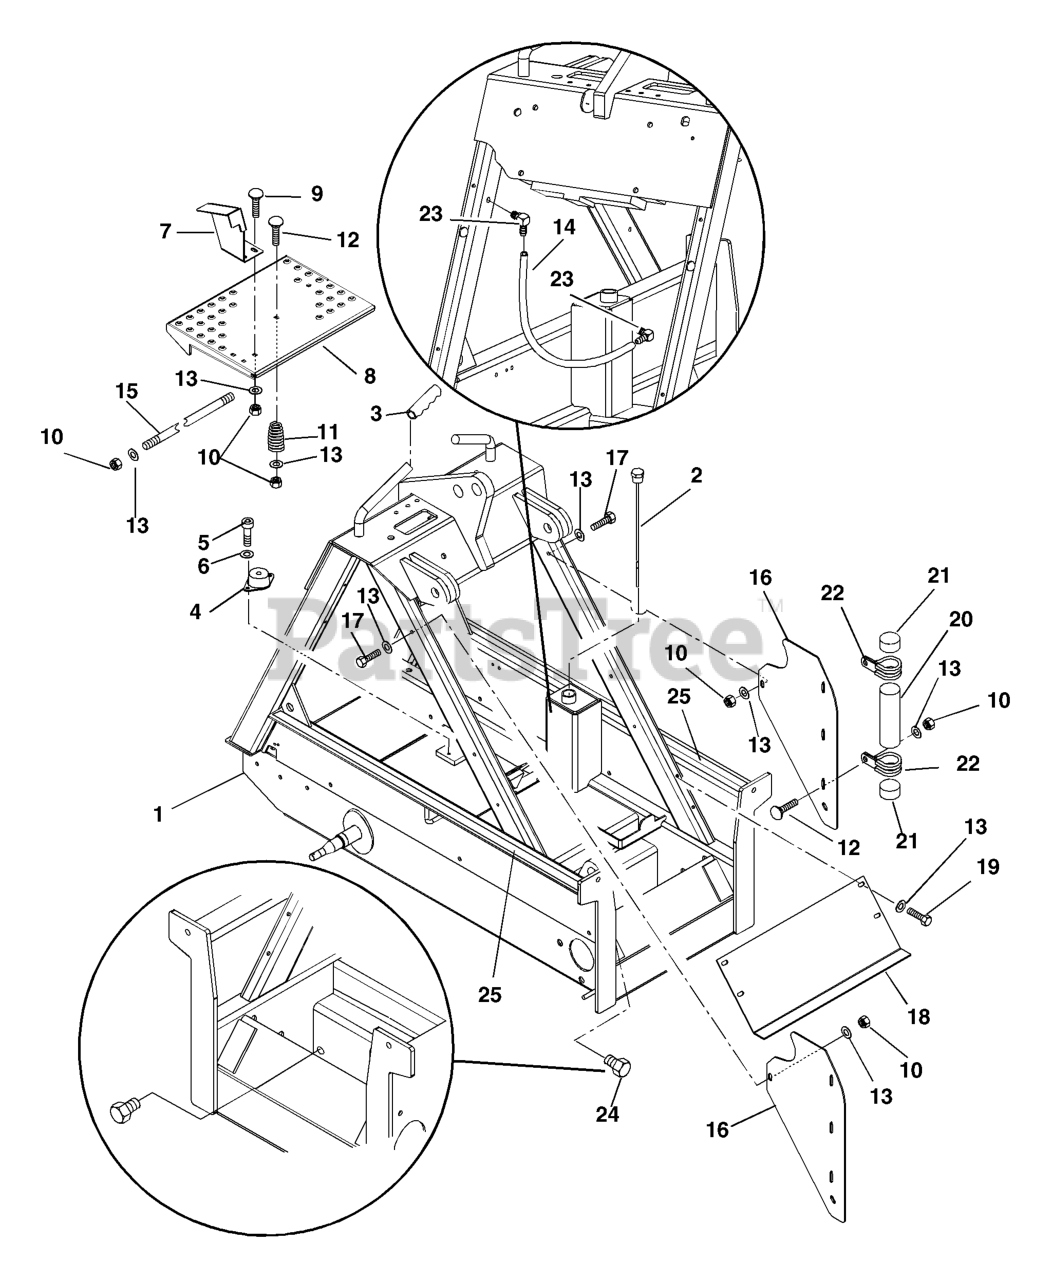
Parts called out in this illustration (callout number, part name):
2	Dipstick
3	Grip-Handle
4	Mount-Engine
5	Screw-Socket Head M8-1.25 x 12
6	Washer-Lock .31 x .078
7	Bracket-Hydraulic Stop
8	Grate-Floor Weldment
9	Bolt-Round Head Square Neck M8-1.25 x 20
10	Nut-Hex Locking Flange M8-1.25
11	Spring-Compression
12	Bolt-Round Head Square Neck M8-1.25 x 25
13	Washer-Flat-Steel .344 x .688 x .065
14	Line-Gas
15	Rod-Pivot
16	Guard-Pinch
17	Bolt, Hex M8-1.25 x 60
18	Plate-Inspection
19	Bolt-Hex M8 x 1.25 x 16
20	Tube-Instruction
21	End-Cap Instruction Tube
22	Clamp-2.00 Diameter with .406 Hole
23	Fitting-Barbed 90 Degree Elbow .125-27M x .25 I.D. Hose
24	Plug, Drain .75-14
25	Gasket-Foam with Adhesive Back 1" x 50' x .25"
